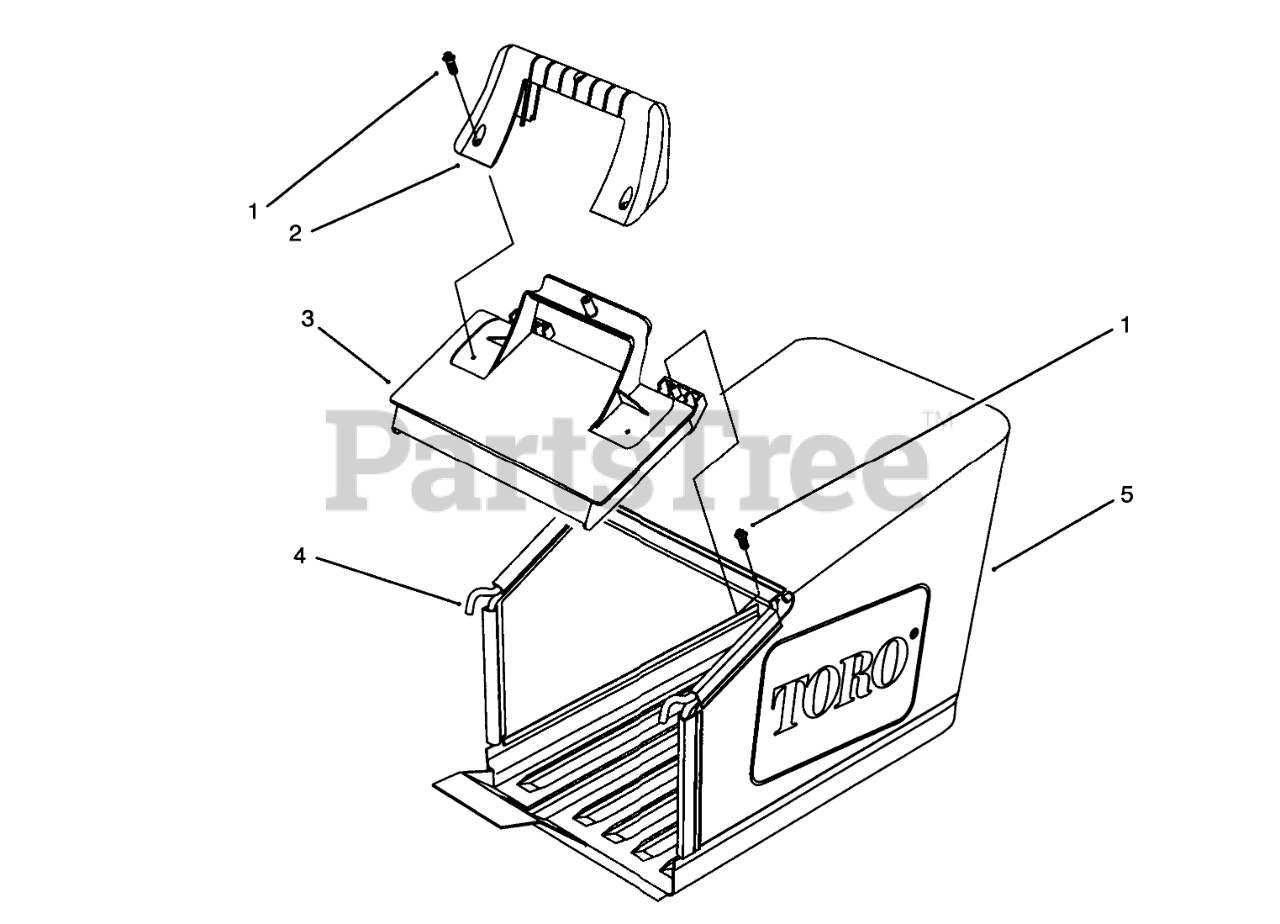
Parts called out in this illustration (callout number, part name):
1	SCREW-PPH
2	HANDLE-DOOR
3	DOOR-BAG
4	Frame
5	BAG-GRASS
